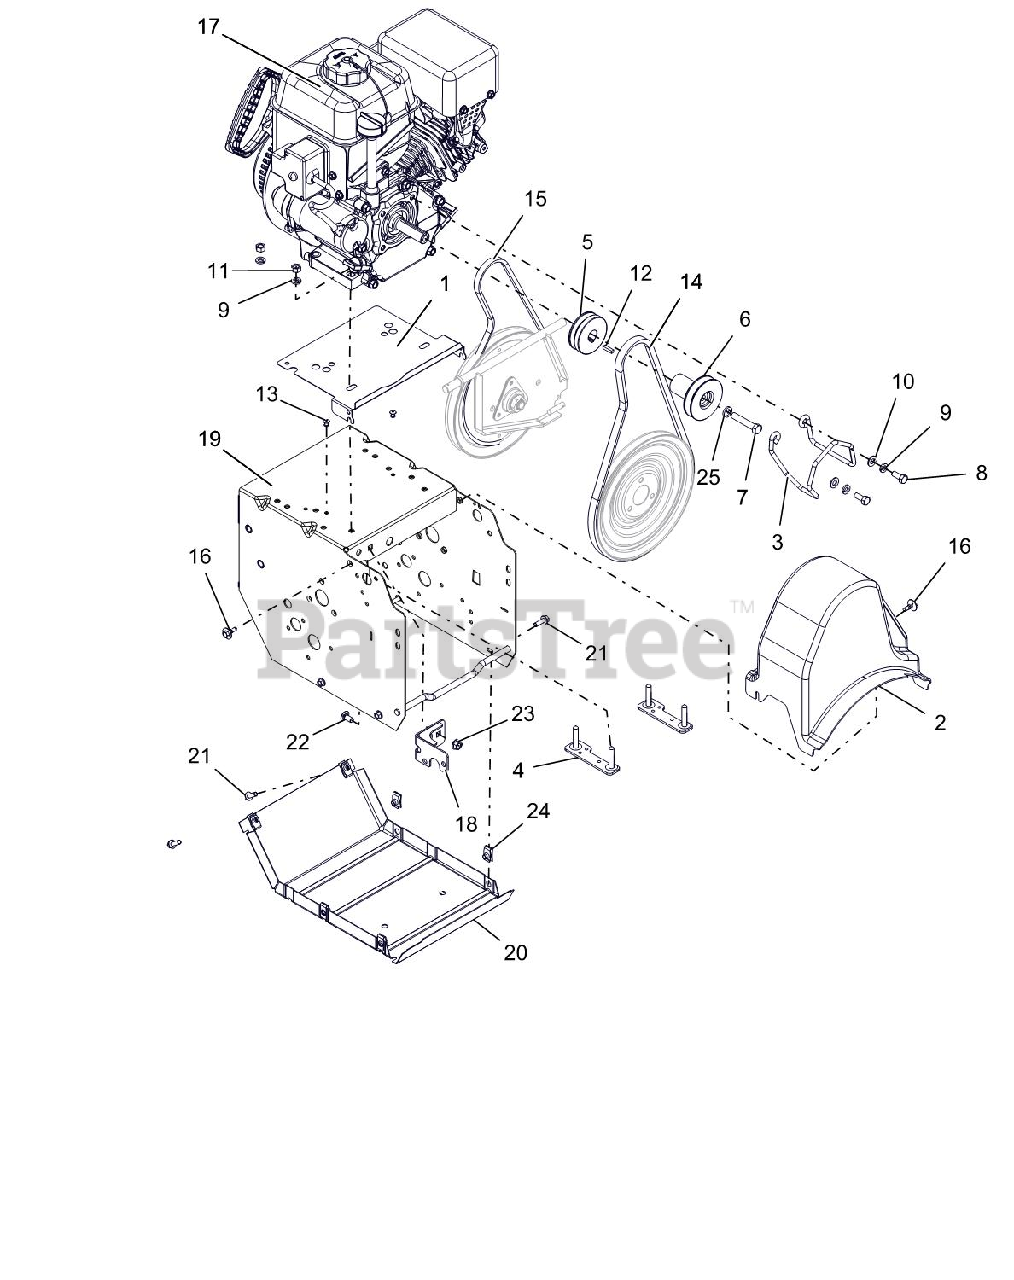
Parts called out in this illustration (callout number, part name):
1	BAFFLE, COMPACT
2	COVER, COMPACT BELT
3	FINGER, BELT
4	STRAP, ENGINE BOLT-WELDMENT
5	SHEAVE, TRACTION-COMPACT TRACK
6	SHEAVE,AUGER 3/4" PM
7	BLT-HEX .38-24X2.0 YWZC
8	BLT-HEX .31-24X.75 YWZC GR5
9	WSHR-LK .312X.097 HVY YWZC
10	@WSHR-FL-STL.344X.688X.065YWZC
11	@NUT-HEX .31-18 YWZC
12	KEY-SQ .188X.75X.188
13	RVT-POP .187 YZ
14	V-BELT, HA-RAW EDGE
15	V-BELT, 3L-WRAPPED
16	SCR-TAP .25-20X.5 CAPTIVE
18	WELDMENT, FRAME BRACKET
19	FRAME, MAIN-WELDMENT
20	COVER, BOTTOM
21	BLT-HEX .25-20X.75 HWH YZ GR5
22	@BLT-RHDSSQNK .31-18X.62 G5YZ
23	@NUT-LK-TOP-FLG .31-18 YWZC
24	NUT-RTNR .25-20X.56
25	WSHR-LK .375X.115 HVY YWZC
